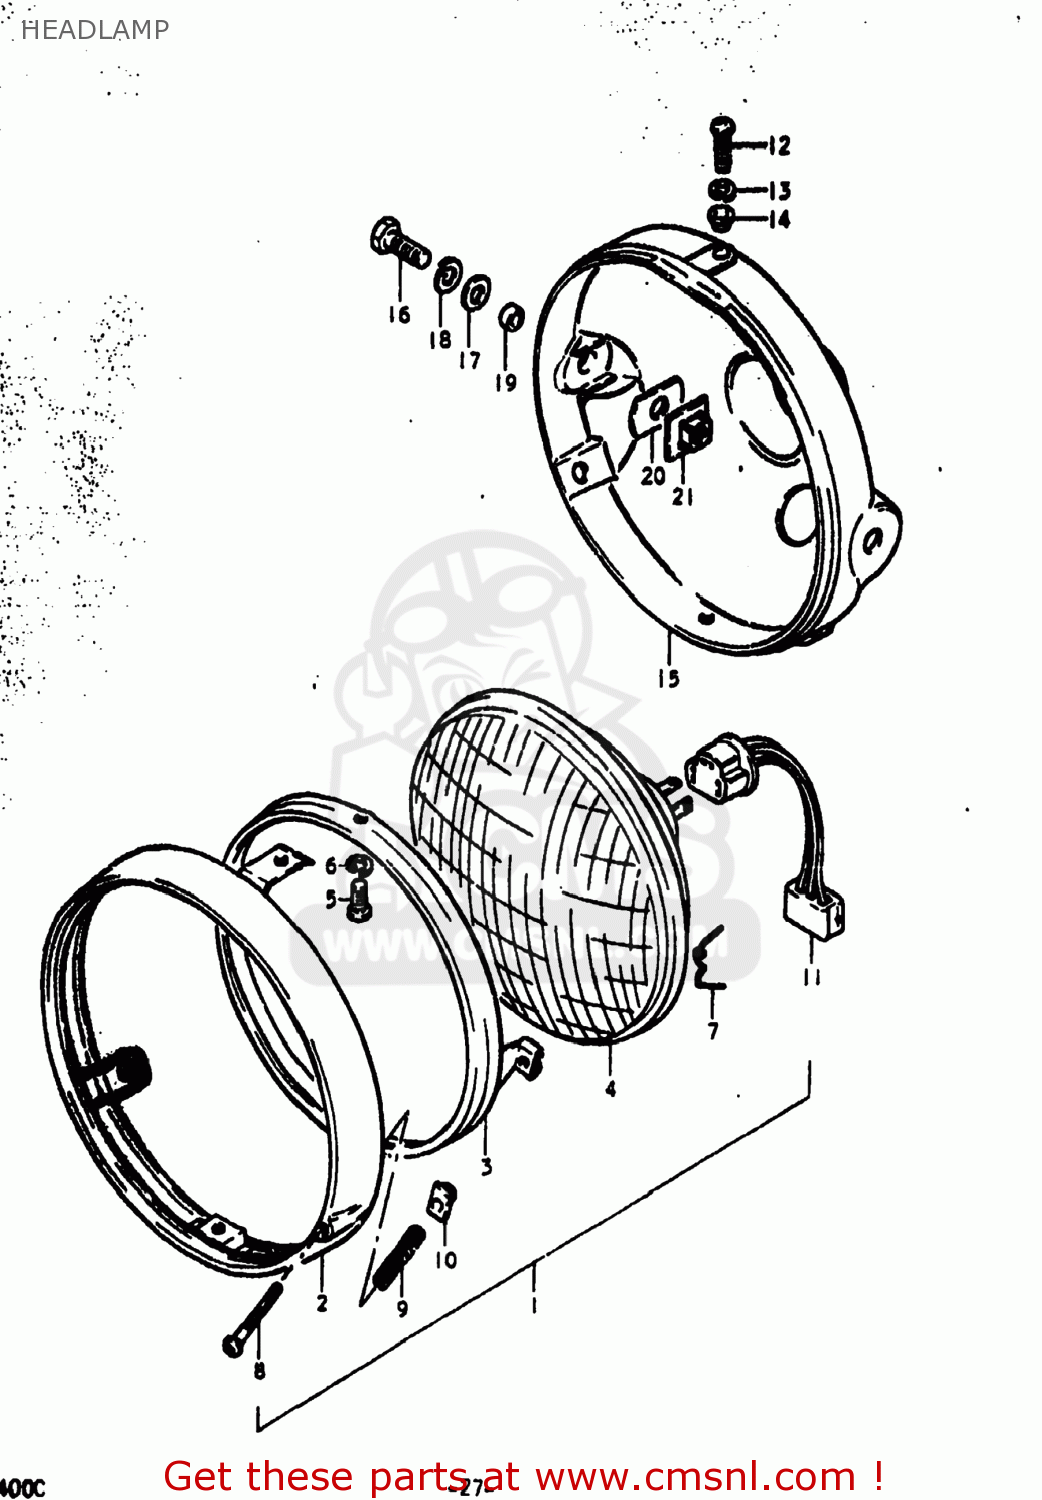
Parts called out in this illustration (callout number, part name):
1	HEADLAMP ASSEMBLY
2	RIM,HEADLAMP
3	RETAINER,HEADLAMP
4	LAMP UNIT
5	SCREW
6	LOCK WASHER
7	SPRING
8	SCREW,HEADLAMP ADJUST
9	SPRING
10	NUT
11	LEAD WIRE,HEADLAMP
12	SCREW
13	WASHER,LOCK
14	WASHER
15	HOUSING,HEADLAMP(BLACK)
16	BOLT
17	WASHER
18	LOCK WASHER
19	SPACER (8.8X12X7)
20	CUSHION
21	PLATE,HEADLAMP HOUSING
